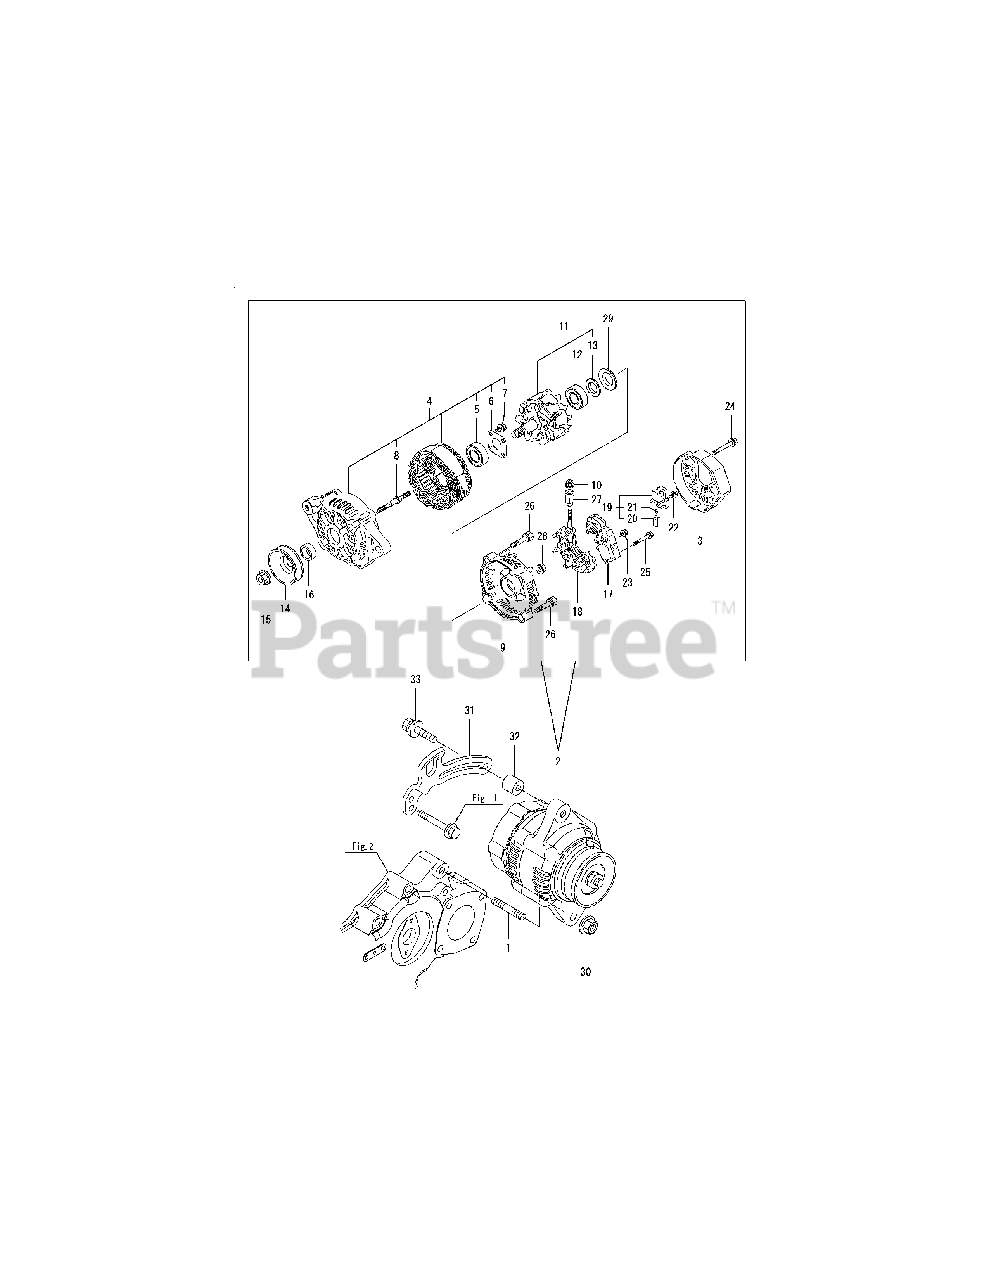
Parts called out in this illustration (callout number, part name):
2	GENERATOR, 12V-40A
4	FLAME ASSY, DRIVE
6	PLATE, RETAINER
9	FLAME ASSY, REAR
13	COVER, BEARING
17	REGULATOR ASSY
27	BUSH, INSULATION
29	WASHER, THRUST
31	ADJUSTER, BELT
33	BOLT, ADJUSTER
